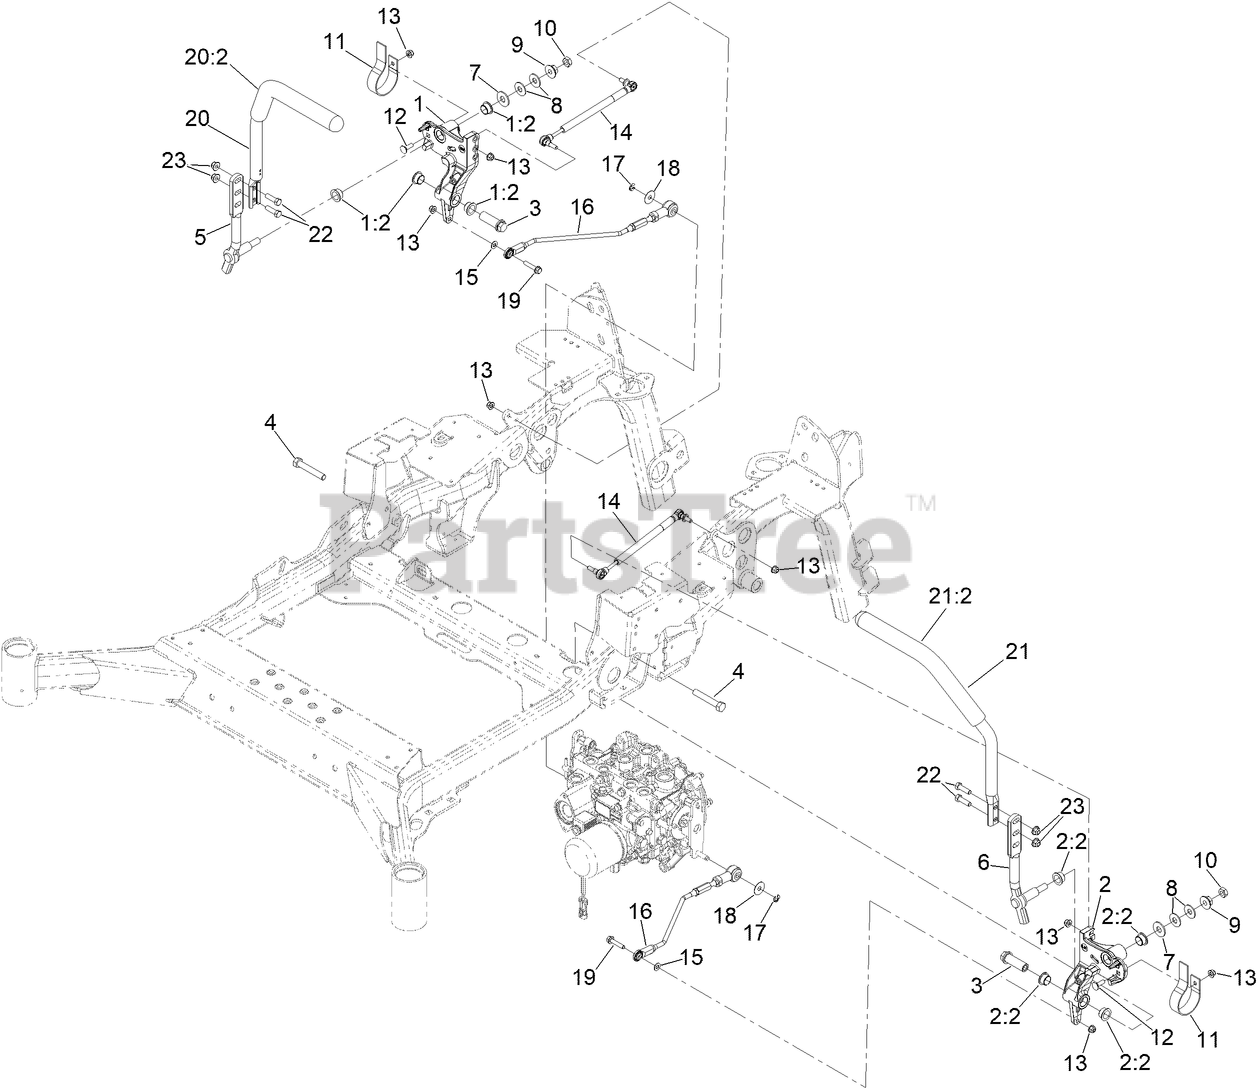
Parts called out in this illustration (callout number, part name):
1	RH MOTION CONTROL AND BUSHING ASM
1:2	BUSHING-FLANGE
2	LH MOTION CONTROL AND BUSHING ASM
2:2	BUSHING-FLANGE
3	HUB-THREADED
4	SCREW-HH
5	LEVER-CONTROL MOTION, RH
6	LEVER-CONTROL MOTION, LH
7	WASHER-FLAT
8	WASHER-SPRING
9	NUT-HF
10	NUT-JAM
11	SPRING-LEAF
12	BOLT-CARR
13	NUT-HF, NI
14	DAMPER, MOTION CONTROL
15	WASHER-PLAIN
16	ASM, FRONT LINKAGE ROD
17	RING-RETAINING
18	WASHER-PLAIN
19	BOLT-SHOULDER,HHF
20	ASM,STEERING HANDLE RH
20:2	GRIP-CONTROL, LEVER
21	ASM,STEERING HANDLE LH
21:2	GRIP-CONTROL, LEVER
22	SCREW-HH
23	NUT-HF, NI
